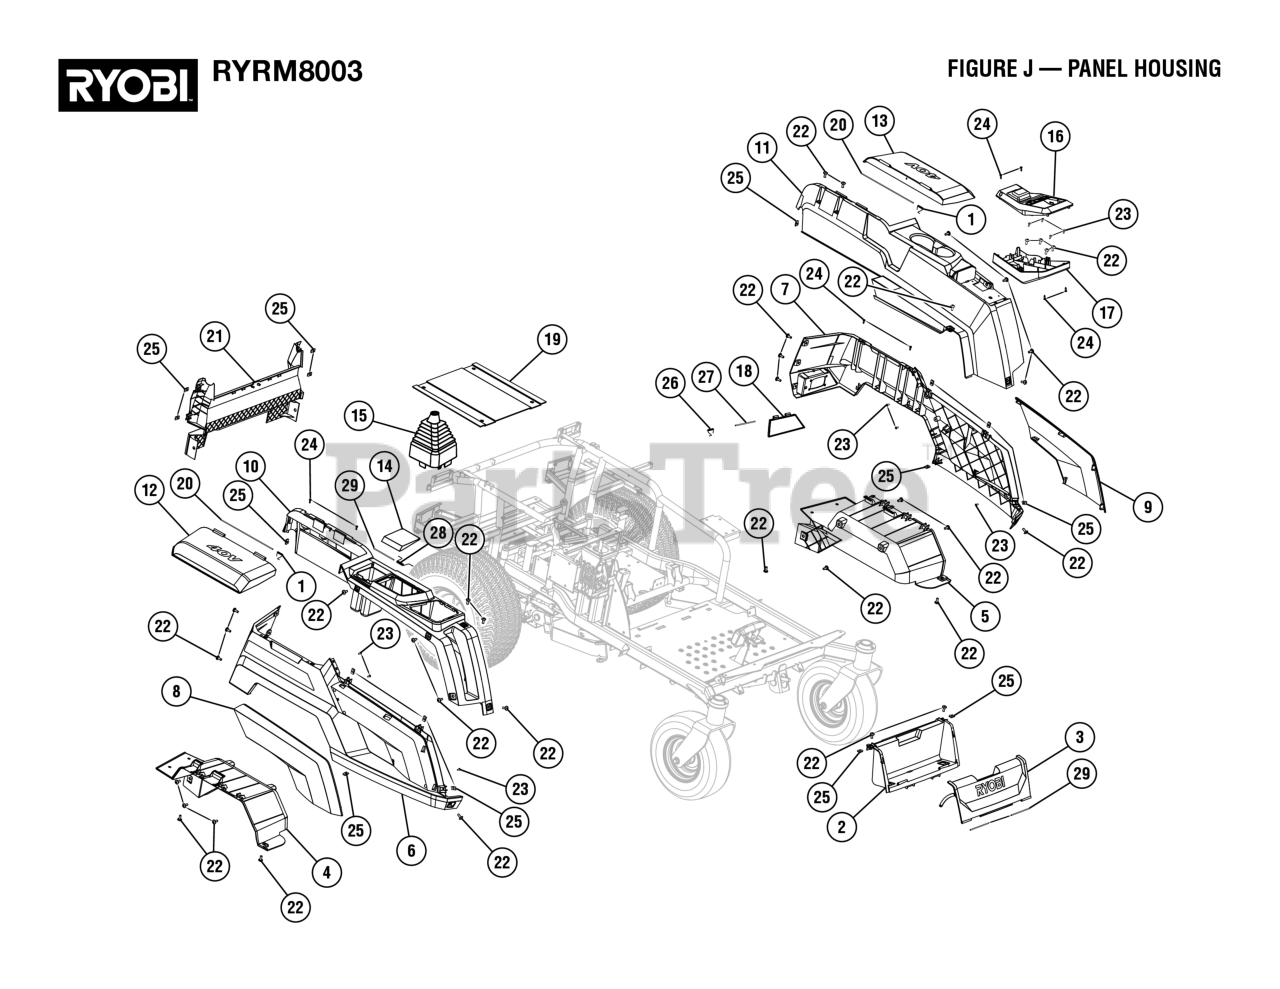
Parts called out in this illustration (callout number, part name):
1	Battery Cover Spring
2	Front Pocket
3	Front Pocket Door
4	Wheel Well (Right)
5	Wheel Well (Left)
6	Fender (Right)
7	Fender (Left)
8	Trim Panel (Right)
9	Trim Panel (Left)
10	Console (Right)
11	Console (Left)
12	40V Battery Lid (Right)
13	40V Battery Lid (Left)
14	Storage Lid
15	Joystick Bellow Assembly
16	LCD Upper Cover
17	LCD Lower Cover
18	Charging Door
19	Controller Cover
20	Battery Cover Hinge Pin
21	Rear Cover
22	Screw (M6 x 10 mm, Soc. Button Hd.)
23	Screw (M4 x 10 mm, Pan Hd.)
24	Screw (M3 x 12 mm, Pan Hd.)
25	Clip-On Nut (M6)
26	Charger Door Spring
27	Charger Door Hinge
28	Storage Bin Spring
29	Storage Box Hinge Pin
30	Storage Bin Spring
